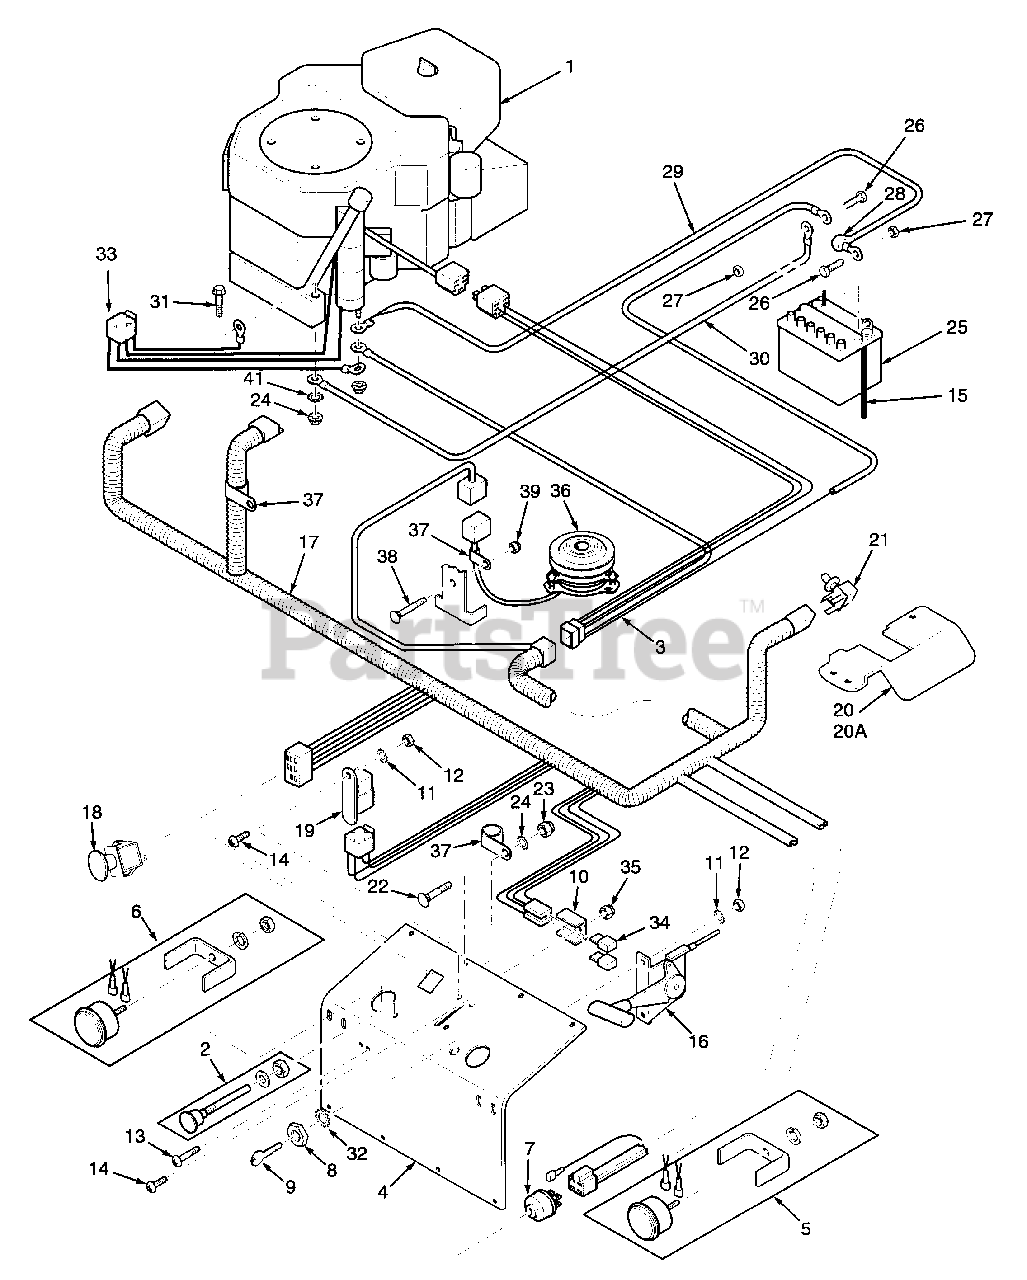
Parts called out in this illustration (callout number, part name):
1	Engine 18 hp Kohler CV
2	Choke Control
3	Adapter
4	Kick Plate
5	Hour Meter
6	Ammeter
7	Key Switch
8	Nut, Hex 5/8-32
9	Key & Ring Assembly
10	Bracket, Fuse Holder
11	Lockwasher, #10 External Tooth
12	Nut, Hex #10-32
13	Screw, Phillips Washer Head #10-32 x 1-1/2"
14	Screw, Phillips Washer Head #10-32 x 1/2"
15	Overflow Tube
16	Throttle Control
17	Wire Harness
18	Switch, Mower Engagement Electric Clutch
19	Relay
20	Neutral Lock Bracket, RH
20A	Neutral Lock Bracket, LH
21	Switch Neutral Lock
22	Bolt, Carriage 5/16-18 x .75"
23	Nut, Elastic Stop 5/16-18
24	Washer, Star 5/16-18
25	Battery
26	Bolt, Hex Head 1/4-20 x 1/2"
27	Nut, Hex 1/4-20
28	Rubber Boot
29	Battery Cable, 25" Red
30	Battery Cable, 27" Black
31	Bolt, Serrated Flange Hex Head 5/16-18 x 1.50"
32	Washer, Star 5/8"
33	Wire Harness w/Relay
34	Fuse, Blade Type 20 amp
35	Nut, Elastic Stop #10-32
36	Electric Clutch
38	Bolt, Carriage 5/16-18 x 3/4"
39	Nut, Elastic Stop 5/16-18
